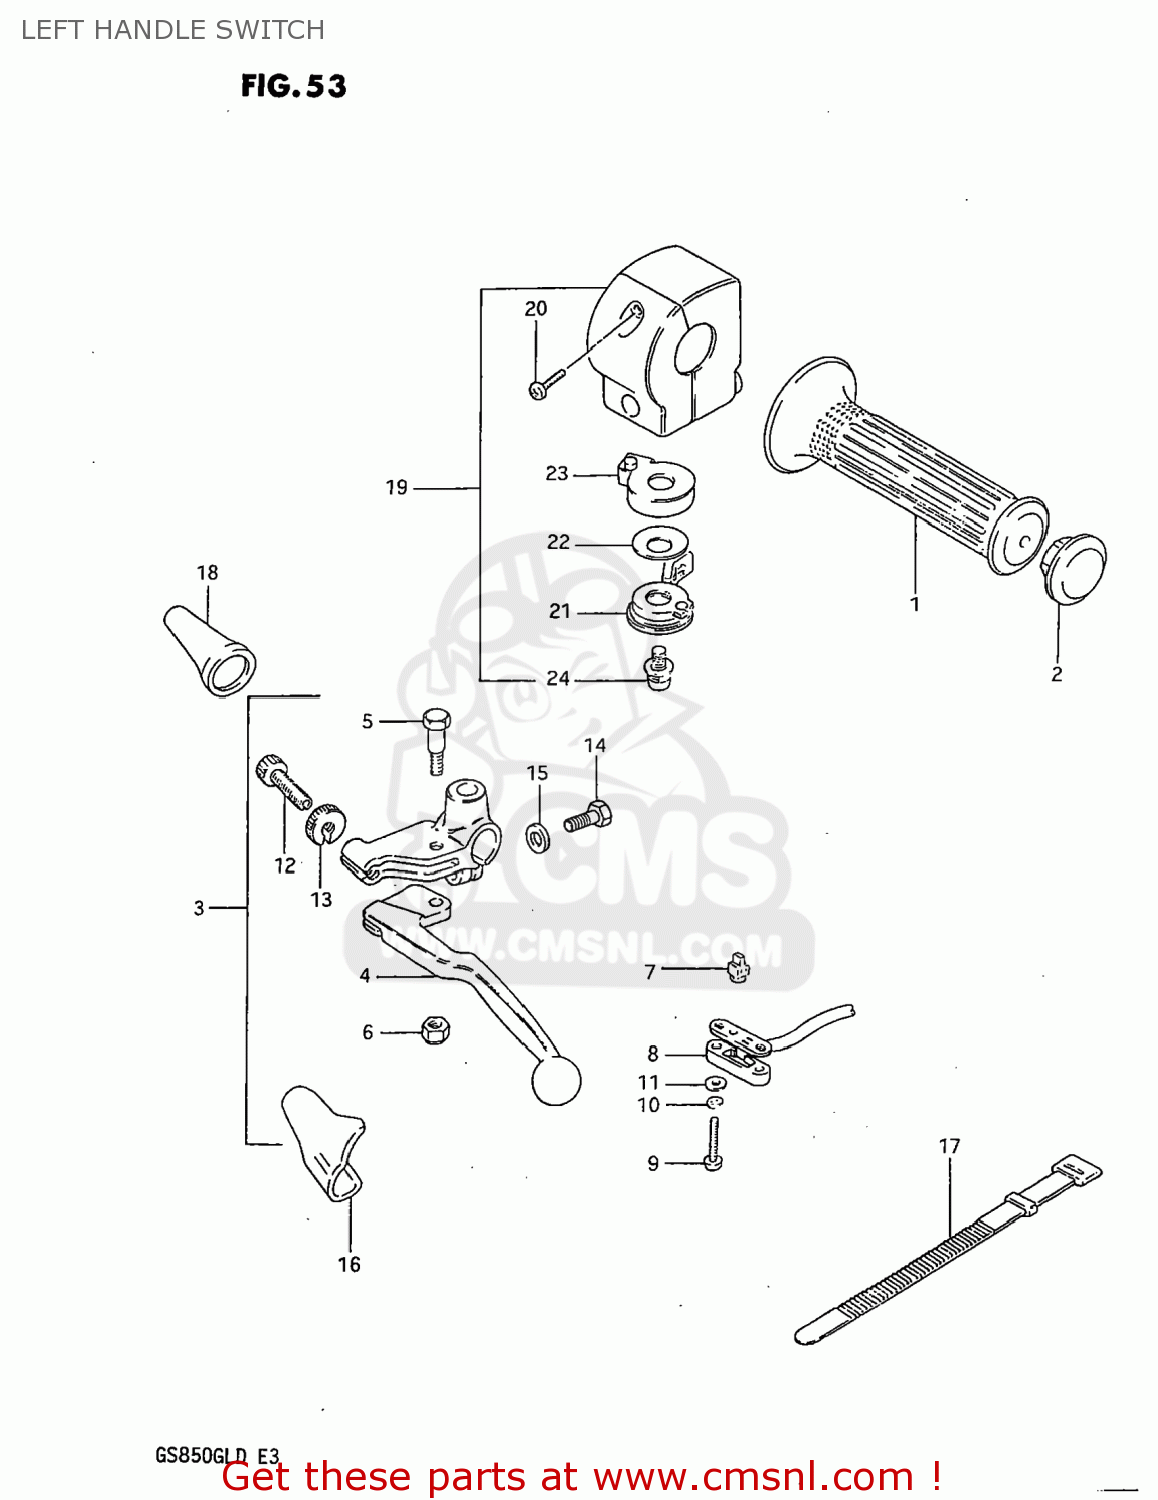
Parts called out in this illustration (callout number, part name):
1	GRIP,LEFT
2	CAP,GRIP END
3	LEVER ASSEMBLY
4	LEVER,CLUTCH
5	BOLT,LEVER
6	NUT 6MM
7	CONTACT,SWITCH
8	COVER,FR BK TERMINAL BASE
9	SCREW
10	LOCK WASHER
11	WASHER
12	ADJUSTER,CABLE
13	NUT,CABLE ADJUSTER
14	BOLT,CLUTCH LEVER HOLDER
15	WASHER
16	COVER,CLUTCH LEVER
17	CLAMP(L:120)
18	BOOT,CLUTCH CABLE
19	SWITCH ASSEMBLY,HANDLE,LEFT
20	SCREW
21	LEVER,STARTER
22	WASHER,ADJUSTER
23	BODY,CHOCK
24	SCREW,CHOKE LE
